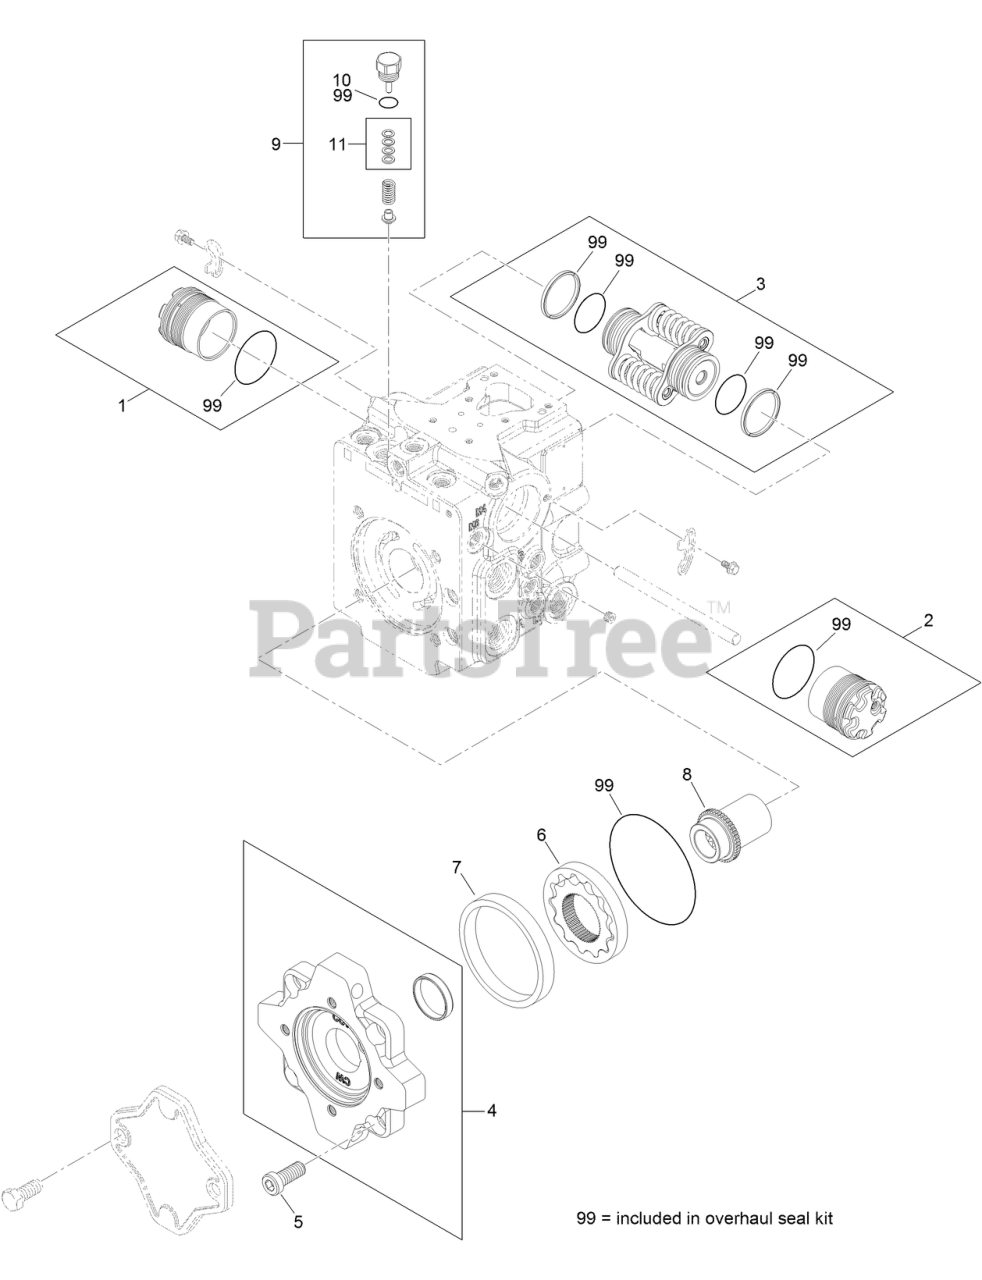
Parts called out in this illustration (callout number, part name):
1	SERVO CYLINDER ASM
2	SERVO CYLINDER ASM
3	SERVO PISTON ASM
4	ADAPTER ASM
6	GEROTOR
7	RING-PUMP, CHARGE
8	COUPLING
9	CHARGE RELIEF KIT
10	O-RING
11	SHIM KIT
99	SEAL KIT
